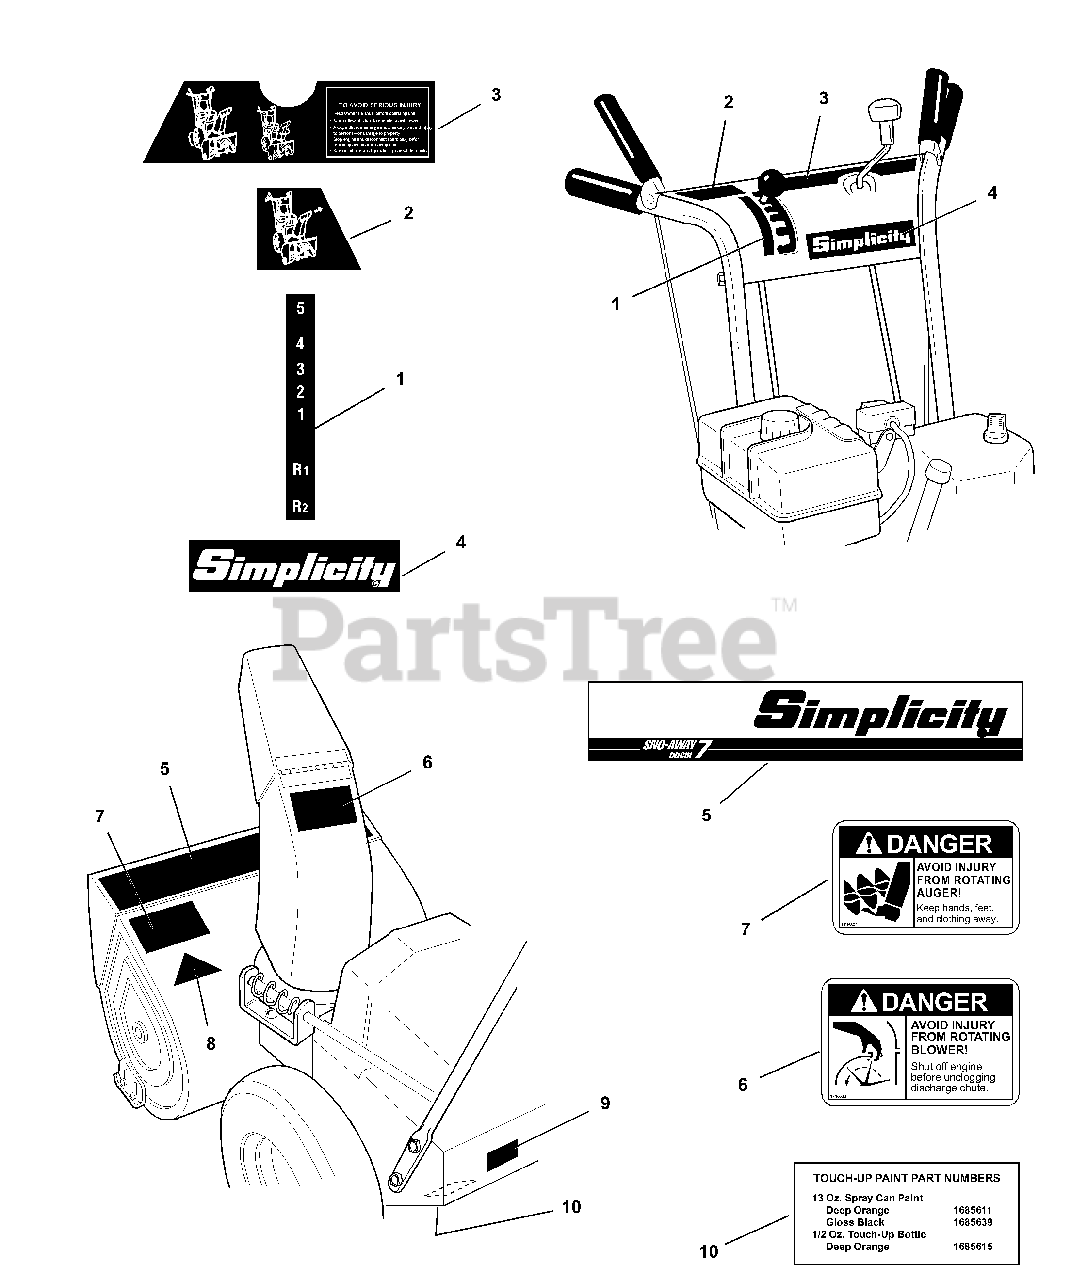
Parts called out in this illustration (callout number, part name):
1	DECAL, Speed Selector
2	DECAL, Auger Control
3	DECAL, Warning / Main Dash Panel
4	DECAL, Simplicity Logo
6	DECAL, Danger, Discharge Chute
7	DECAL, Danger, Auger
8	DECAL, OPEI
9	DECAL, Touch-up Paint ID
10	I.D. Tag
